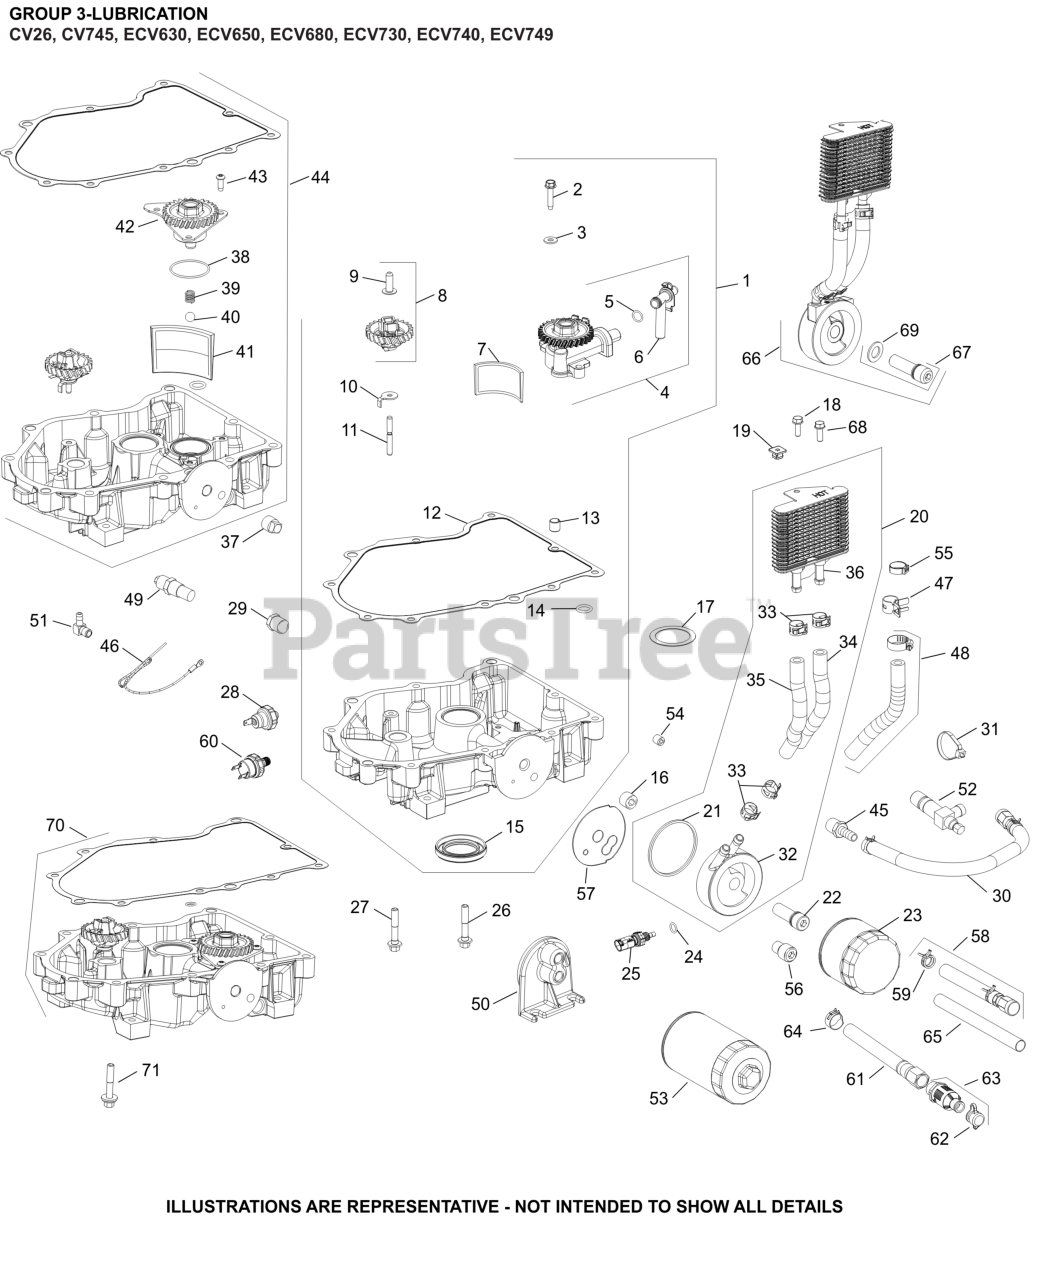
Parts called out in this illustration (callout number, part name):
8	KIT, GOVERNOR GEAR W/PIN
9	PIN, GOVERNOR REGULATING
10	TAB, LOCKING
12	KIT, OIL PAN GASKET
19	NUT, PLASTIC - BLACK
21	O-RING, OIL COOLER
23	OIL FILTER
24	O-RING (.5" DIA)
26	SCREW, HEX FLANGE
27	SCREW, FLG M8X1.25X45
29	PLUG, HD PIPE 3/8"
33	CLAMP, HOSE LOW PROFILE
38	O-RING (1.78" DIA)
39	SPRING, COMPRESSION
40	PRESSURE RELIEF BALL
41	SCREEN, OIL
42	PUMP, OIL ASSEMBLY
43	SCREW, BUTTON HEAD
45	FITTING, BARBED
48	KIT, HOSE 140MM
58	HOSE, OIL ASSEMBLY
60	SWITCH, PRESSURE
65	SLEEVE, ANTI ABRASION
66	KIT, OIL COOLER
67	KIT, OIL FILTER NIPPLE
68	SCREW, HEX HEAD
69	WASHER, FLAT
NI	PAN, ASSEMBLY OIL (SERVICE)
NI	SHAFT, GOVERNOR GEAR
